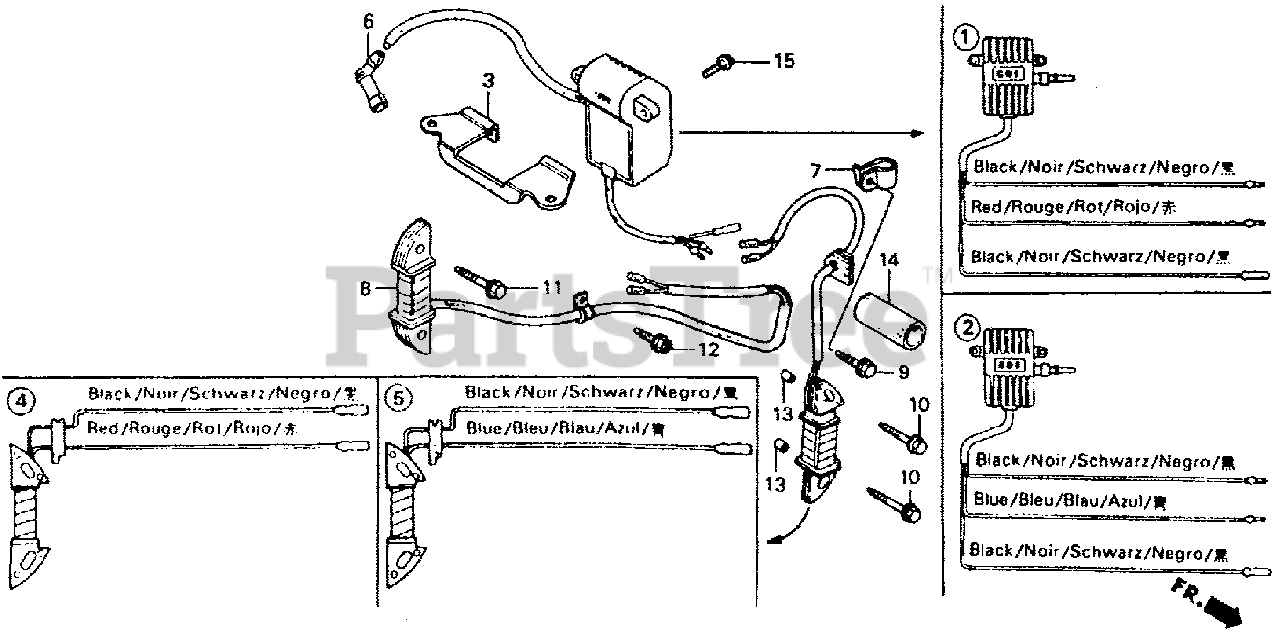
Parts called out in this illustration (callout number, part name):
1	MODULE, IGNITION CONTROL (CDI)
3	STAY, IGNITION CONTROL MODULE
4	COIL ASSY., EXCITER
6	CAP ASSY., NOISE SUPPRESSOR
7	CLAMP, IGNITION WIRE
9	BOLT, FLANGE (6X12) (CT200)
10	BOLT, FLANGE (6X28)
13	PIN A, DOWEL (8X14)
14	TUBE, VINYL (22X27X60) (NOT AVAILABLE)
15	BOLT, FLANGE (6X12)
